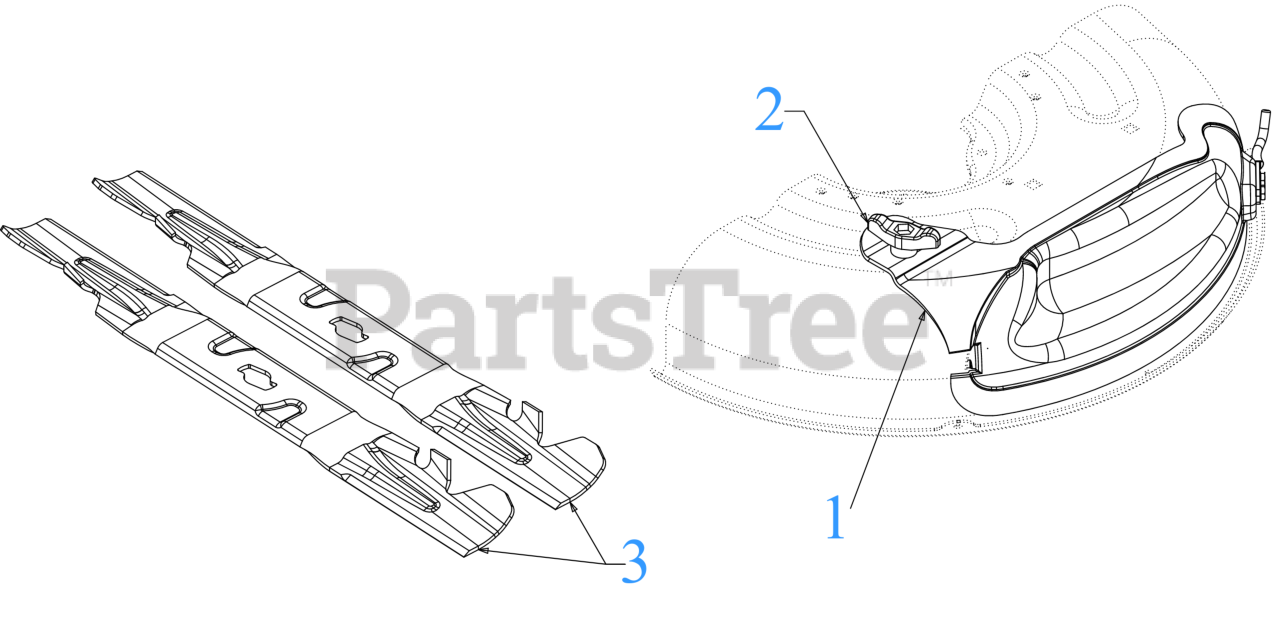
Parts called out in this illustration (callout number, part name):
1	MULCH PLUG ASSEMBLY
2	WING KNOB 5/16-18
3	23.25" XTREME BLADE (2IN1) (S SHAPE CENTER HOLE)
